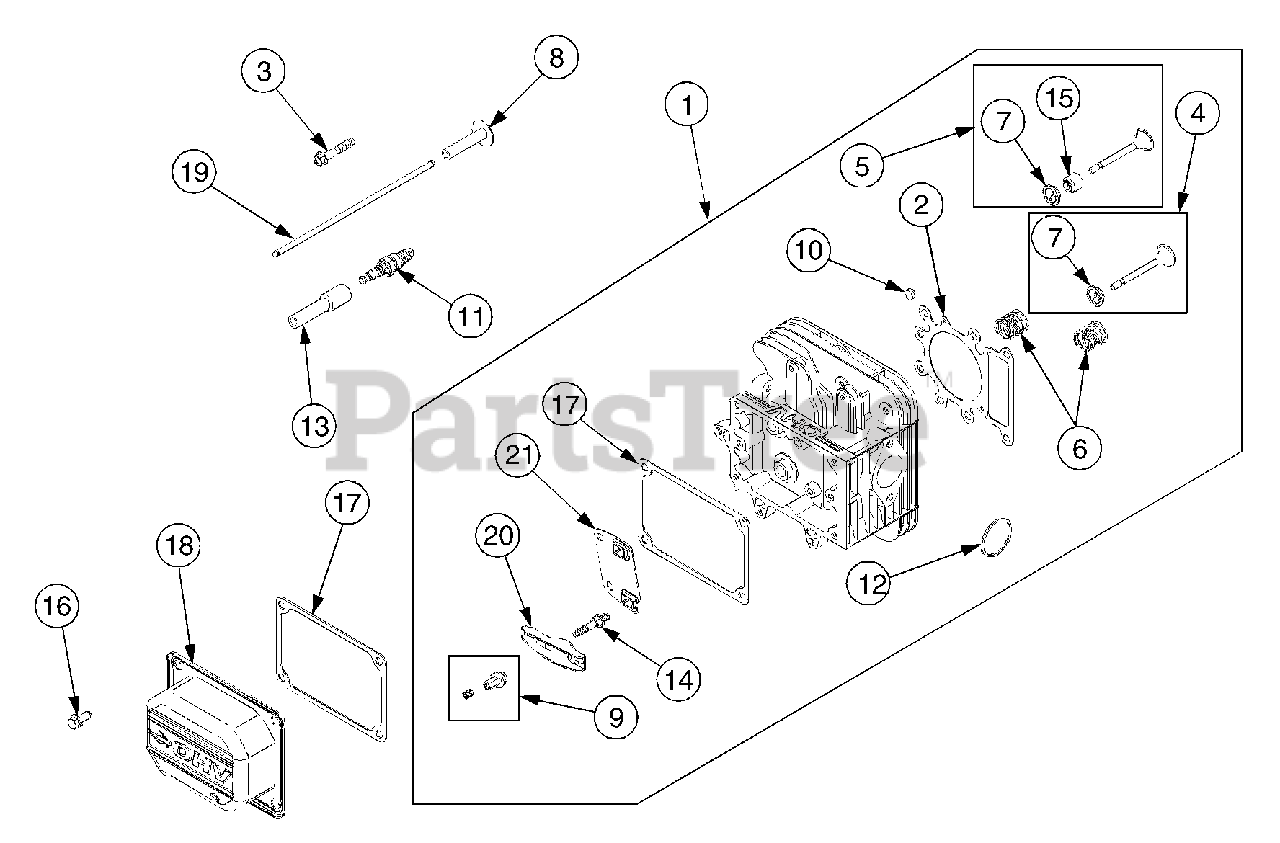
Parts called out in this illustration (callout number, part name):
1	Head, Cylinder
2	Gasket, Cylinder Head
3	Screw, Cylinder Head
4	Valve, Exhaust
5	Valve, Intake
6	Spring, Valve
7	Retainer, Valve
8	Tappet, Valve
9	Adjuster, Rocker Arm
10	Cap, Valve
11	Spark Plug (RC12YC)
12	O-Ring Seal (Intake Manifold)
13	Boot, Spark Plug
14	Stud, Rocker Arm
15	Seal, Valve
16	Screw (Rocker Cover)
17	Gasket, Rocker Cover
18	Cover, Rocker
19	Rod, Push (Intake)
20	Arm, Rocker
21	Guide, Push Rod
